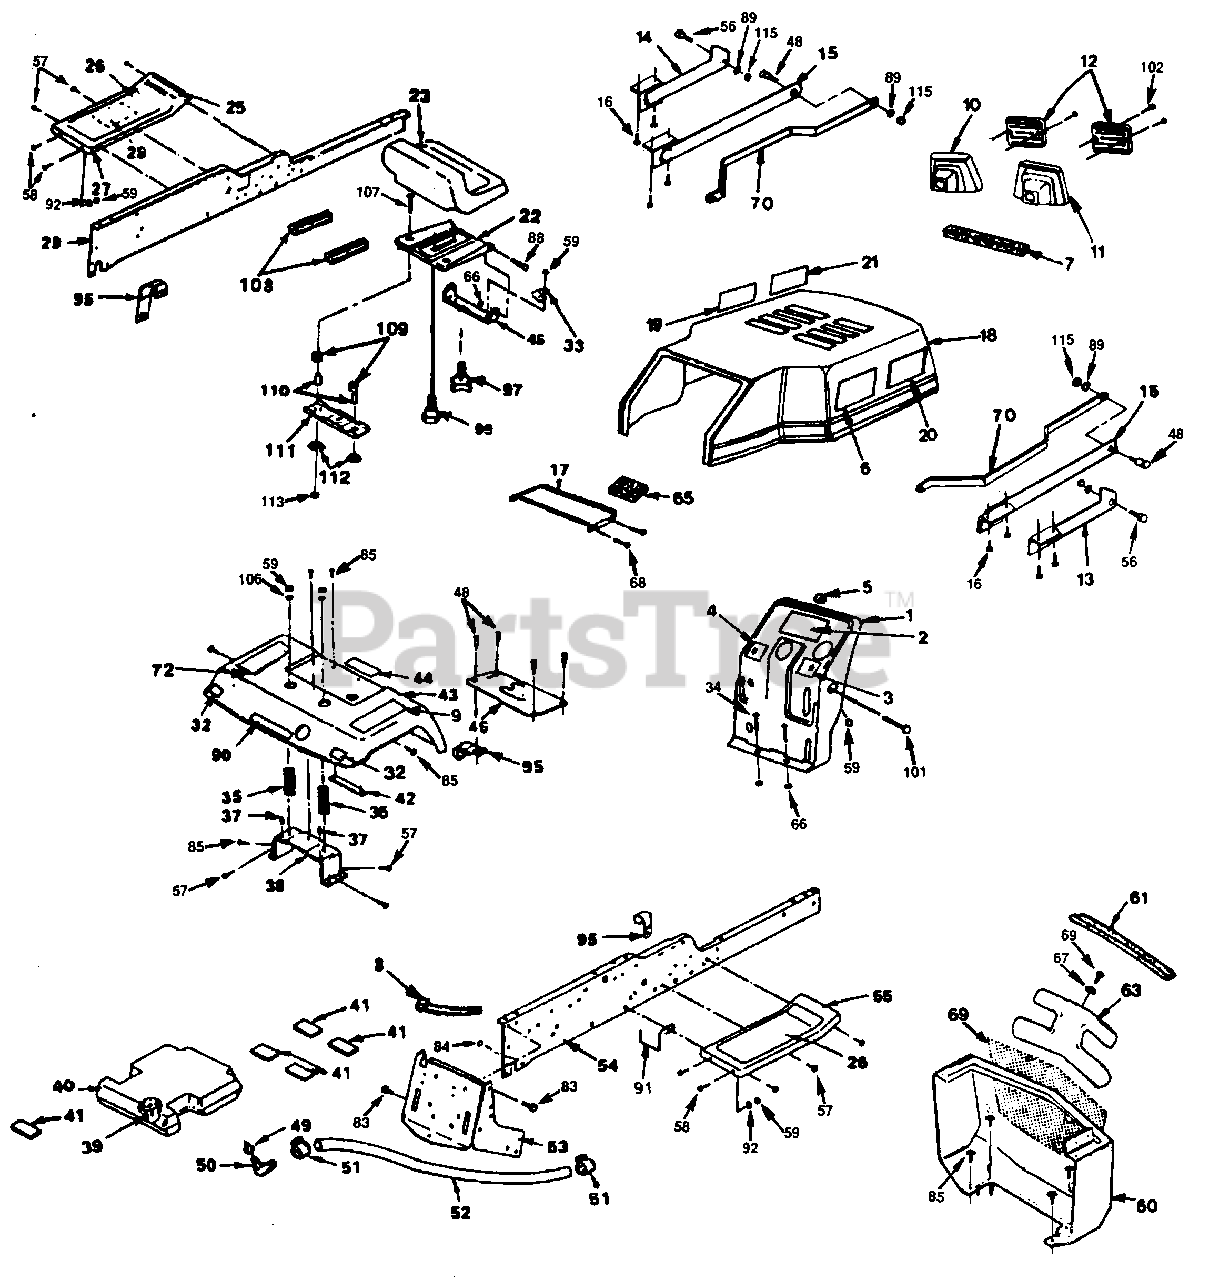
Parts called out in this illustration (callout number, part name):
2	Dash Decal (AYP part number)
3	Lift Decal (AYP part number)
4	Clutch Decal (AYP part number)
5	Dash Plug (AYP part number)
6	R.H. Decal (AYP part number)
7	Foam Strip (AYP part number)
8	Tie Cable (AYP part number)
9	R.H. Fender Decal (AYP part number)
10	L.H. Bezel (AYP part number)
11	R.H. Bezel (AYP part number)
12	Lens (AYP part number)
13	R.H. Strap Assembly Hinge (AYP part number)
14	L.H. Strap Assembly Hinge (AYP part number)
15	Rear Hinge Strap Assembly (AYP part number)
16	Wsh. Hd. Hex Screw #13-16 x 5/8 (AYP part number)
17	Battery Support (AYP part number)
18	Hood (AYP part number)
19	L.H. Decal (AYP part number)
20	R.H. Poulan Decal (AYP part number)
21	L.H. Poulan Decal (AYP part number)
22	Seat Pan (AYP part number)
23	Seat (AYP part number)
25	Clutch/Brake Decal (AYP part number)
26	Footrest Pad (AYP part number)
27	L.H. Footrest (AYP part number)
28	Drive Belt Schematic Decal (AYP part number)
29	L.H. Frame Rail (AYP part number)
32	Taillight Reflector (AYP part number)
33	Insulated Clip (AYP part number)
34	Machine Head Screw 5/16-18 x 3/4 (AYP part number)
35	Compression Spring (AYP part number)
37	Push Nut (AYP part number)
38	Fender Bracket (AYP part number)
39	Fuel Cap (AYP part number)
40	Fuel Tank (AYP part number)
41	Spacer Pad (AYP part number)
42	Fender Strap (AYP part number)
43	Fender (AYP part number)
44	Caution Decal (AYP part number)
45	Pivot Seat Bracket (AYP part number)
46	Shift-Gate Cover (AYP part number)
48	Shoulder Bolt (AYP part number)
49	Bushing (AYP part number)
50	Fuel Tank Stem (AYP part number)
51	Hose Clamp (AYP part number)
52	Fuel Line (AYP part number)
53	Drawbar (AYP part number)
54	R.H. Frame Rail (AYP part number)
55	R.H. Footrest (AYP part number)
56	Shoulder Bolt (AYP part number)
57	Rolling Thread Washer Hex Screw (AYP part number)
58	Hex Bolt 3/8-16 x 3/4 (AYP part number)
59	Lock Nut 3/8-16
60	Grill (AYP part number)
61	Foam Strip
63	Insert Grill
64	Grill Screen
65	Foam Strip (AYP part number)
66	Crownlock Nut 5/16-18
67	Washer 7/32 x 5/8 x 16 Ga. (AYP part number)
68	Carriage Bolt 5/16-18 x 3/4
69	Hex Screw (AYP part number)
70	Grill Brace (AYP part number)
71	Hex Screw 1/4-20 x 1/2 (AYP part number)
72	L.H. Fender Decal (AYP part number)
83	Hex Bolt (AYP part number)
84	Lock Nut 7/16-14 (AYP part number)
85	Rolling Thread Washer Hex Screw (AYP part number)
88	Shoulder Bolt (AYP part number)
89	Washer (AYP part number)
91	Lower Belt Retainer (AYP part number)
92	Washer (AYP part number)
95	Insulated Clip (AYP part number)
97	Knob (AYP part number)
99	Shoulder Bolt (AYP part number)
101	Hex Bolt 3/8-16 x 1-1/2 (AYP part number)
102	Pan Hd. Screw (AYP part number)
106	Washer (AYP part number)
107	Carriage Bolt 1/4-20 x 1-1/4 (AYP part number)
108	Foam Strip (AYP part number)
109	Compression Spring (AYP part number)
110	Split Spacer (AYP part number)
111	Switch Bracket (AYP part number)
112	Snap Bushing (AYP part number)
113	Flange Lock Nut (AYP part number)
115	Crownlock Nut (AYP part number)
